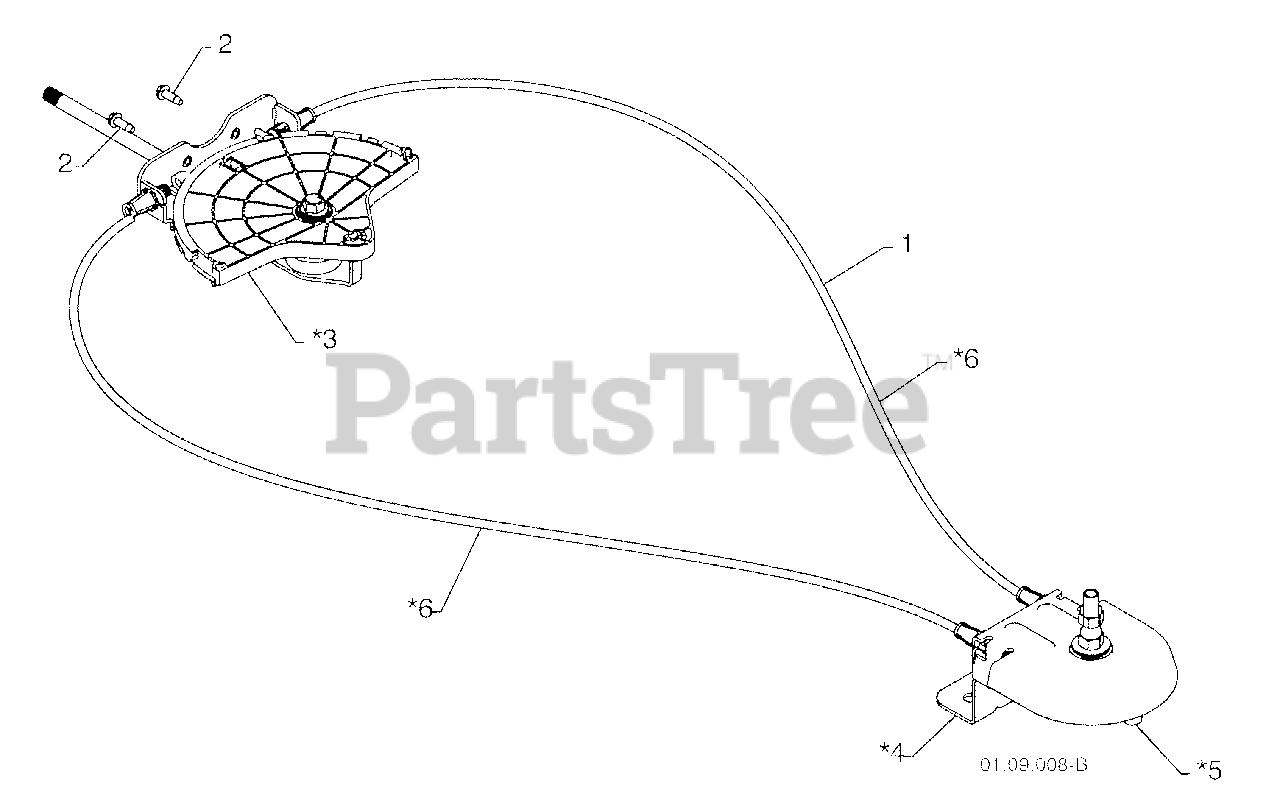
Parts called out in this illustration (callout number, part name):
1	LEVER/CABLE ROTATOR ASSEMBLY GRAY
2	SCREW 10-24 X .625
3	ROTATOR HEAD
4	ROTATOR PIVOT BRACKET
5	PULLEY PIVOT
6	CABLE ASSEMBLY GRAY
